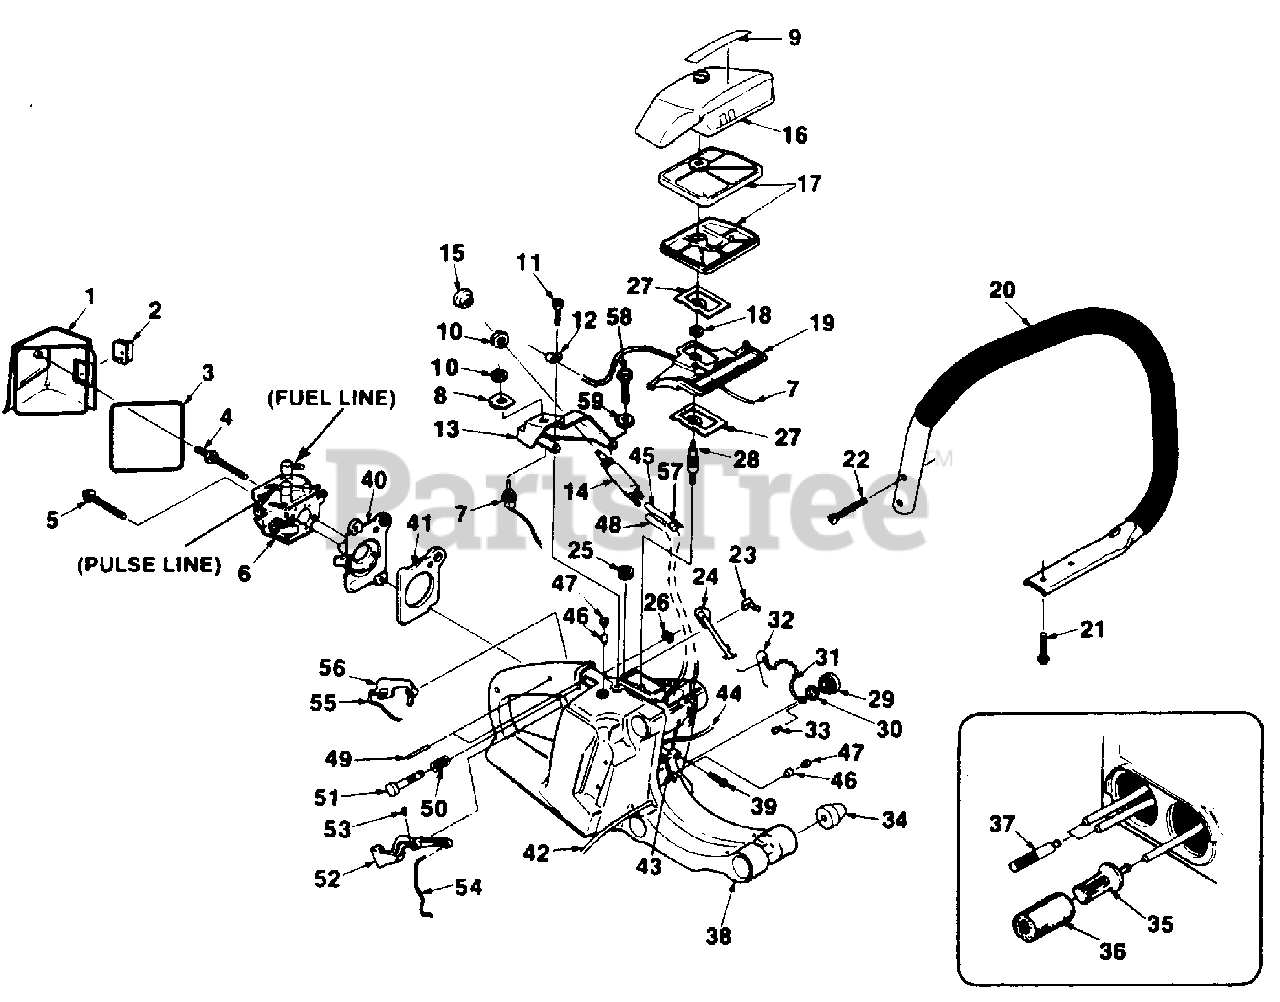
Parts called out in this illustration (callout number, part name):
1	COVER- Carburetor
2	GROMMET (Hi-Lo)
3	GASKET- Carburetor
4	STUD- Shoulder
5	SCREW- Hex Sems (10-24 x 17/8")
6	CARBURETOR (Walbro)
7	SWITCH & LEAD
8	PLATE- Indicating
9	LABEL- Warning
10	NUT- Toggle switch
11	SCREW- Hex Sems hd. (10-24 x 1/2")
12	CLAMP- Wire
13	PANEL- Rear
14	PUMP- Manual oil
16	COVER- Air filter
17	FILTER- Air
18	RING- Retaining
19	SUPPORT- Filter cover
20	HANDLE BAR
21	SCREW- Hex Sems (10-24 x 7/8")
22	SCREW- (10-24 x 1 1/4")
23	RETAINER- Choke
24	ROD- Choke
25	BOOT- Throttle rod
26	RING- Retaining
27	GASKET FILTER & SUPPORT
28	STUD- Threaded
29	CAP- Fuel (red)
30	GASKET- Fuel & Oil Cap
31	BEAD- Chain
32	RETAINER- Filler cap
33	SCREW- Plastite
34	ISOLATOR
35	FILTER- Fuel
36	ELEMENT- Filter
37	FILTER- Oil
38	HOUSING- Engine
39	SCREW- Soc hd. (8-32 x 1/2")
40	ADAPTER- Carburetor
41	SPACER- Carburetor
42	TUBING- 6 3/4" (auto pick up)
43	TUBING- 4 3/4" (pulse line)
44	TUBING- 8 3/4" (fuel line pick up)
45	TUBING- 5" (Man. delivery)
46	VALVE- Check
47	FILTER- 11/32"
48	TUBING- 9 3/4" (man pick up)
49	PIN- Trigger
50	SPRING- Compression
51	PIN- Throttle lock
53	SCREW- Set (6-32 x 1/4")
54	ROD- Throttle
55	SPRING- Flat
56	LOCK- Trigger
58	SCREW- Hex hd. (10-24 x 5/8")
59	WASHER- Lock
